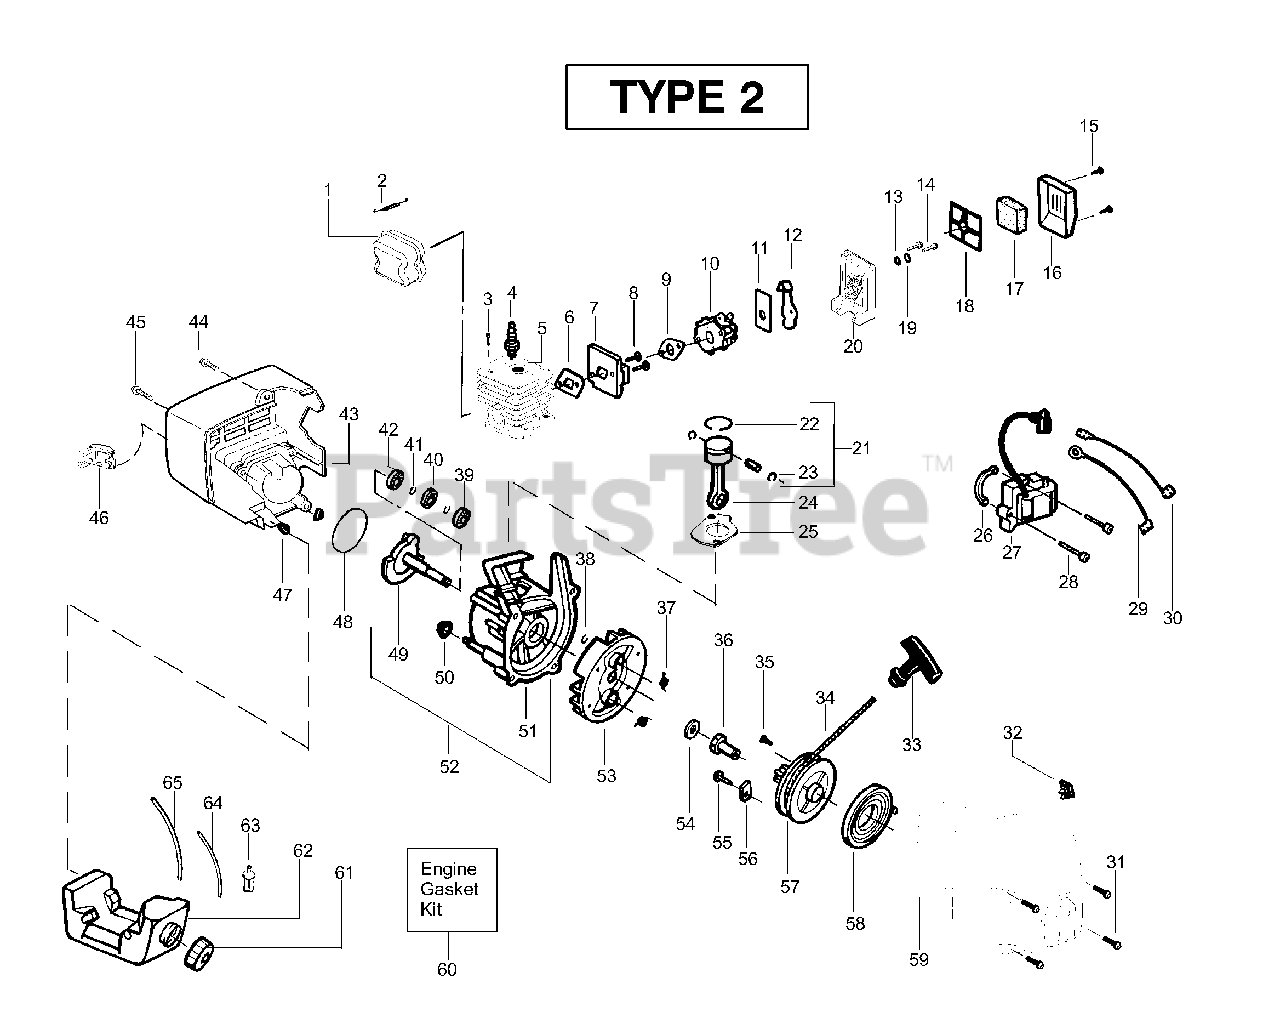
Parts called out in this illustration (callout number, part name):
1	Kit - Muffler
2	Muffler Spring
3	Screw-Cylinder
4	Spark Plug (RCJ 6Y)
5	Kit - Cylinder
6	Gasket-Cyl/Carb.(kit)
7	Adaptor-carb.
9	Gasket-Carb.(kit)
10	Kit-Carb. (WA226)
11	Plate-Choke Mounting
12	Lever-Choke
16	Cover-Air Box
17	Foam-Air Filter
18	Plate-Air Filter Support
19	Spacer-Choke
21	Kit - Piston
22	Piston Ring
23	Retainer-Piston Pin
24	Assy-Connecting Rod
25	Gasket-Cylinder(kit)
26	Spacer-Module
27	Ignition Module
29	Assy-Ground Wire
30	Assy-Leadwire
31	Screw
32	Kit-Switch
33	Handle-Starter
34	Kit - Rope
36	Coupling-Drive
37	Spring-Starter Dog
38	Retain. Ring-C'shaft
39	Bearing-Outer
40	Seal-C'case
41	Retainer Ring-C'case
42	Bearing-Inner
45	Screw
46	Guard-Muffler
47	Isolator-Shroud
48	O-Ring-C'case(kit)
49	Assy-Crankshaft
50	Isolator-Crankcase
51	Assy-Crankcase
52	Assy-C'case & C'shaft
53	Assy-Flywheel
54	Washer-Flat
56	Retainer-Pulley
57	Kit-Starter Pulley
58	Spring-Starter
59	Assy-Fan Housing
60	Kit-Engine Gasket
61	Assy-Fuel Cap
62	Assy-Fuel Tank
63	Assy-Fuel Pickup
64	Kit-Fuel Line
65	Kit-Fuel Line
